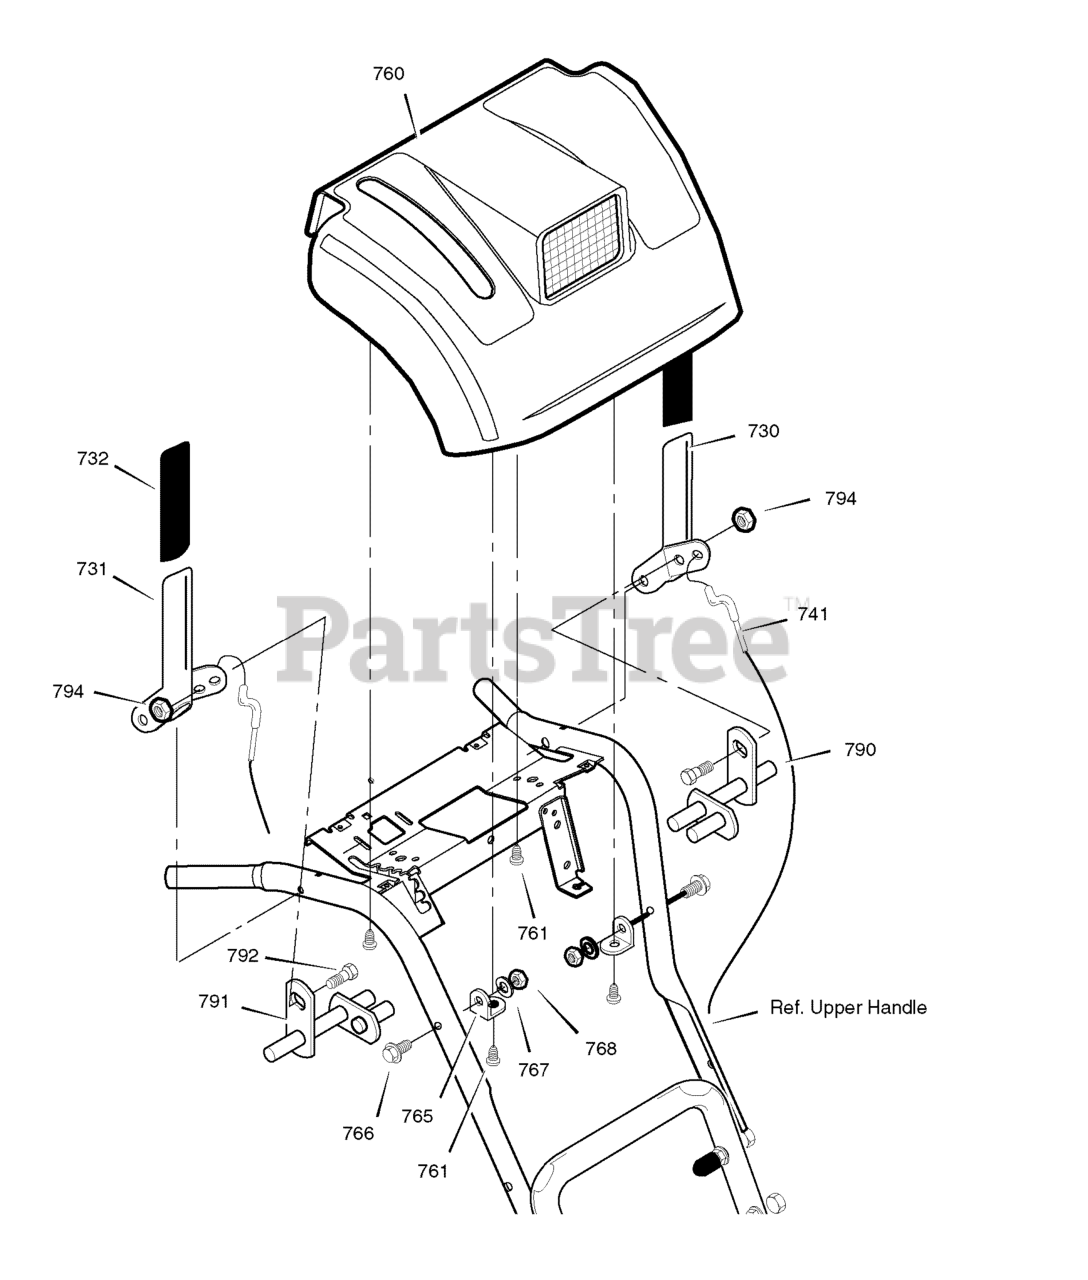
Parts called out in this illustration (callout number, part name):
730	CLUTCH HANDLE LH
731	CLUTCH HANDLE RH
732	GRIP, CLUTCH LEVER
741	CABLE,FR-DR P5 5-13B
760	PANEL, CONTROL
765	BRACKET, PANEL
766	SCREW, 5/16-18 X 1.75
767	WASHER
768	NUT, 5/16-18
790	ROD ASSEMBLY RH
791	ROD ASSEMBLY LH
792	BOLT, 1/4-20 X 0.50
794	NUT, 1/4-20
